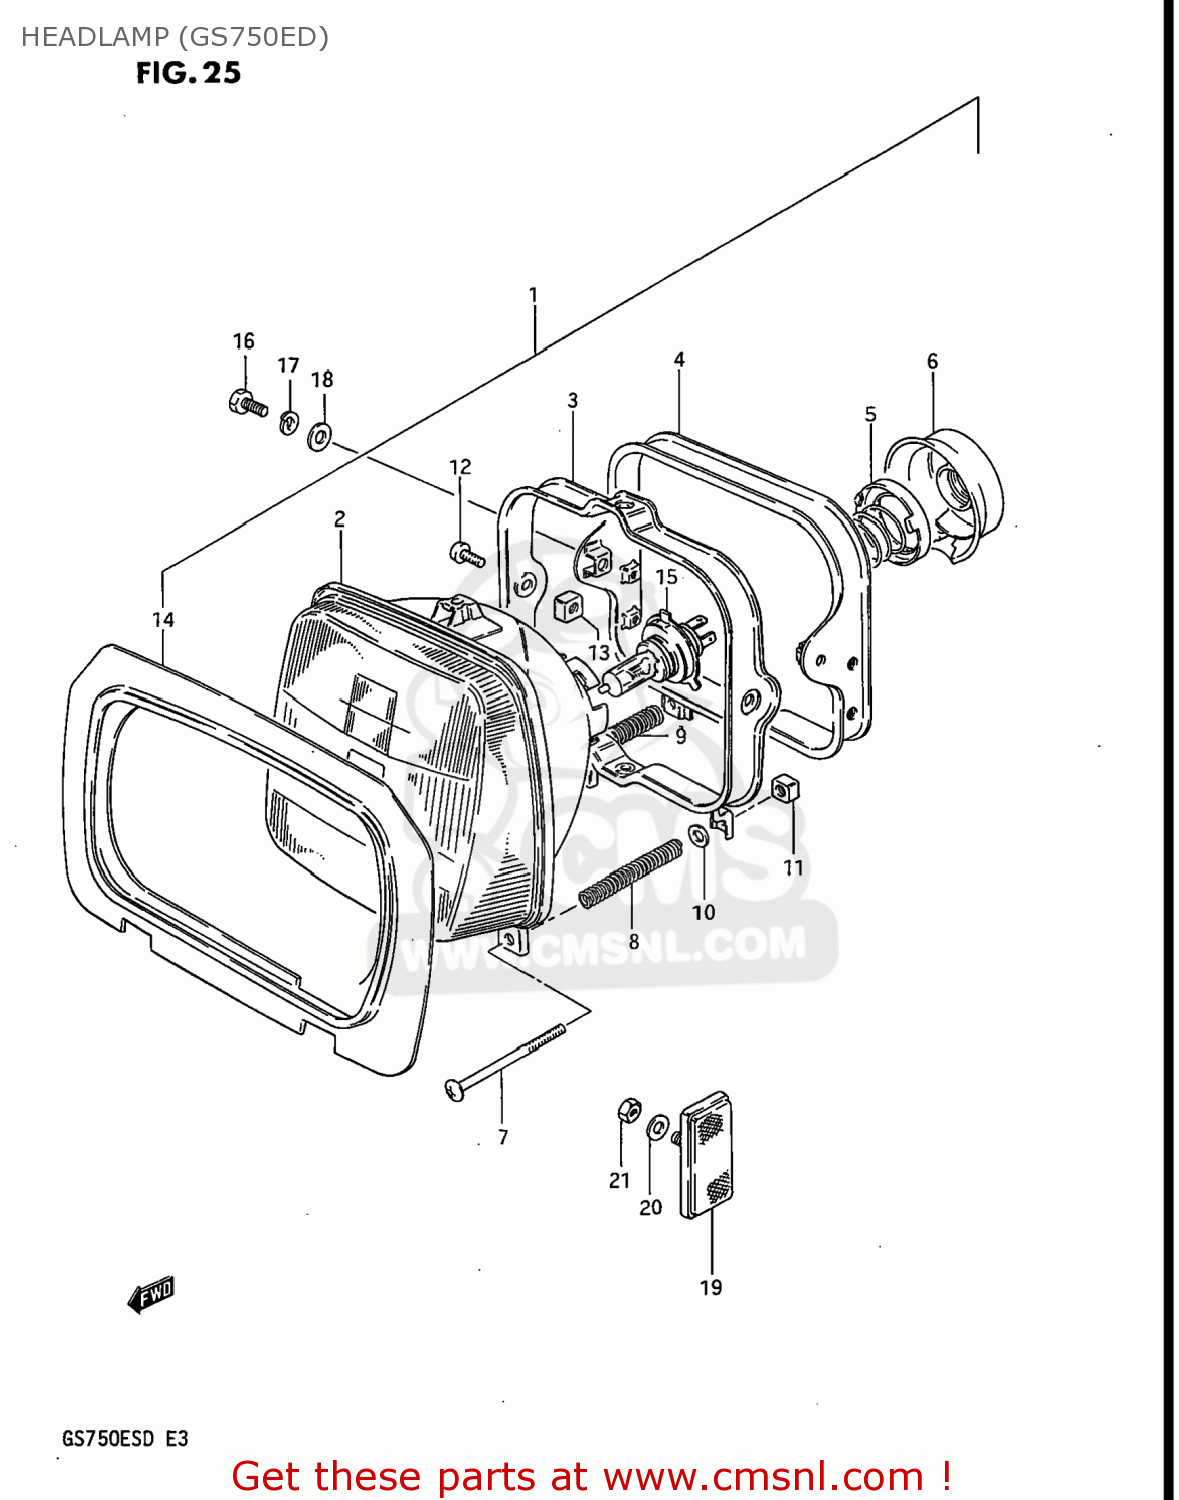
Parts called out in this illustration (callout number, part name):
1	LAMP ASSEMBLY,HEAD
2	LAMP UNIT
3	RING,MOUNTING
4	HOUSING
5	HOLDER
6	COVER,HEADLAMP SOCKET
7	SCREW,HEADLAMP ADJUST
8	SPRING,HEADLAMP ADJUST
9	SPRING
10	WASHER
11	NUT
12	SCREW
13	NUT
14	SHADE
15	BULB(12V60/55W,H4)
16	BOLT
17	LOCK WASHER
18	WASHER
19	REFLEX REFLECTOR ASSEMBLY
20	WASHER
21	NUT
